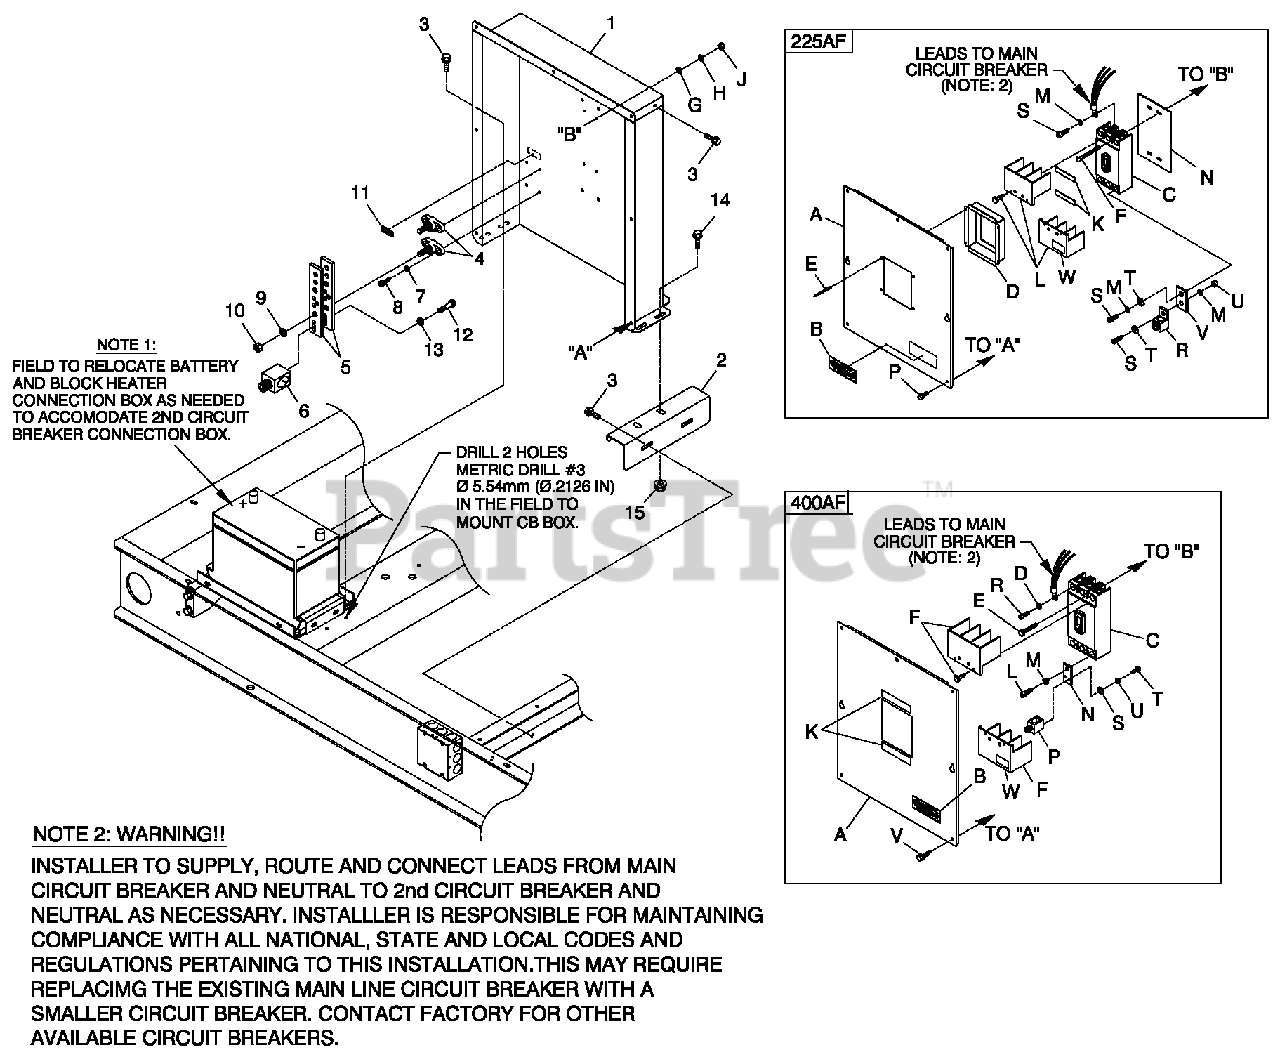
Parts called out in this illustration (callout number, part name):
1	BOX 2ND CB 225/400AF WIDE
2	BRACKET 2ND CB BOX 5.4L 1800
3	SCREW THF M6-1 X 16 N WA Z/JS
4	JUNCTION BLOCK 3/8-16
5	BUSBAR NEUTRAL BLOCK 390
6	LUG SLDLSS 600/250-1/0 X 1/4-28
7	WASHER LOCK M5
8	SCREW PHTT M5-0.8 X 16 ZYC
9	WASHER LOCK 3/8
10	NUT HEX 3/8-16 STEEL
11	DECAL NEUTRAL
12	SCREW HHC 1/4-28 X 3/4 G5
13	WASHER LOCK 1/4-M6 SS
14	SCREW HHFC M6-1.0X20 G8.8
15	NUT TOP LOCK FL M6-1.0
A	COVER CBC2-C4225AF
B	DECAL DANGER HIGH VOLTAGE
C	CB 0100A 3P 480V 225AF
D	COVER CB DISH 225AF
E	RIVET POP .125 X .275 SS
F	SCREW RHM #8-32X3-1/4
G	WASHER FLAT #8 ZINC
H	WASHER LOCK #8-M4
J	NUT HEX #8-32 STEEL
K	TAPE ELEC 1/2 FOAM
L	TERMINAL COVER CB W/HDWR
M	WASHER LOCK M8-5/16
N	INSULATOR CB 225AF
P	SCREW THF M6-1 X 16 N WA Z/JS
R	LUG SLDLSS 300 MCM-6 AL/CU
S	SCREW SHC M8-1.25X20 G8
T	WASHER FLAT 5/16-M8 ZINC
U	NUT HEX M8-1.25 G8 CLEAR ZINC
V	BUS BAR 200A LUG ADAPTOR
W	DECAL TERMINAL SHOCK HZD BI
A	COVER CBC2-C4400AF
C	CB 0300A 3P 480V 400AF
D	WASHER LOCK M10
E	SCREW RHM 10-32X4
F	TERMINAL COVER CB W/HDWR
G	WASHER FLAT #10 ZINC
H	WASHER LOCK #10
J	NUT HEX #10-32 STEEL
L	SCREW SHC M10-1.5 X 25 G12.9
M	WASHER LOCK M10
N	BUS BAR CB ADAPTER 225-400A
P	LUG SLDLSS 600/250-1/0 X 1/4-28
R	SCREW SHC M10-1.5 X 25 G12.9
S	WASHER FLAT 1/4-M6 ZINC
T	SCREW HHC 1/4-28 X 1/2 G5
U	WASHER LOCK M6-1/4
V	SCREW THF M6-1 X 16 N WA Z/JS
